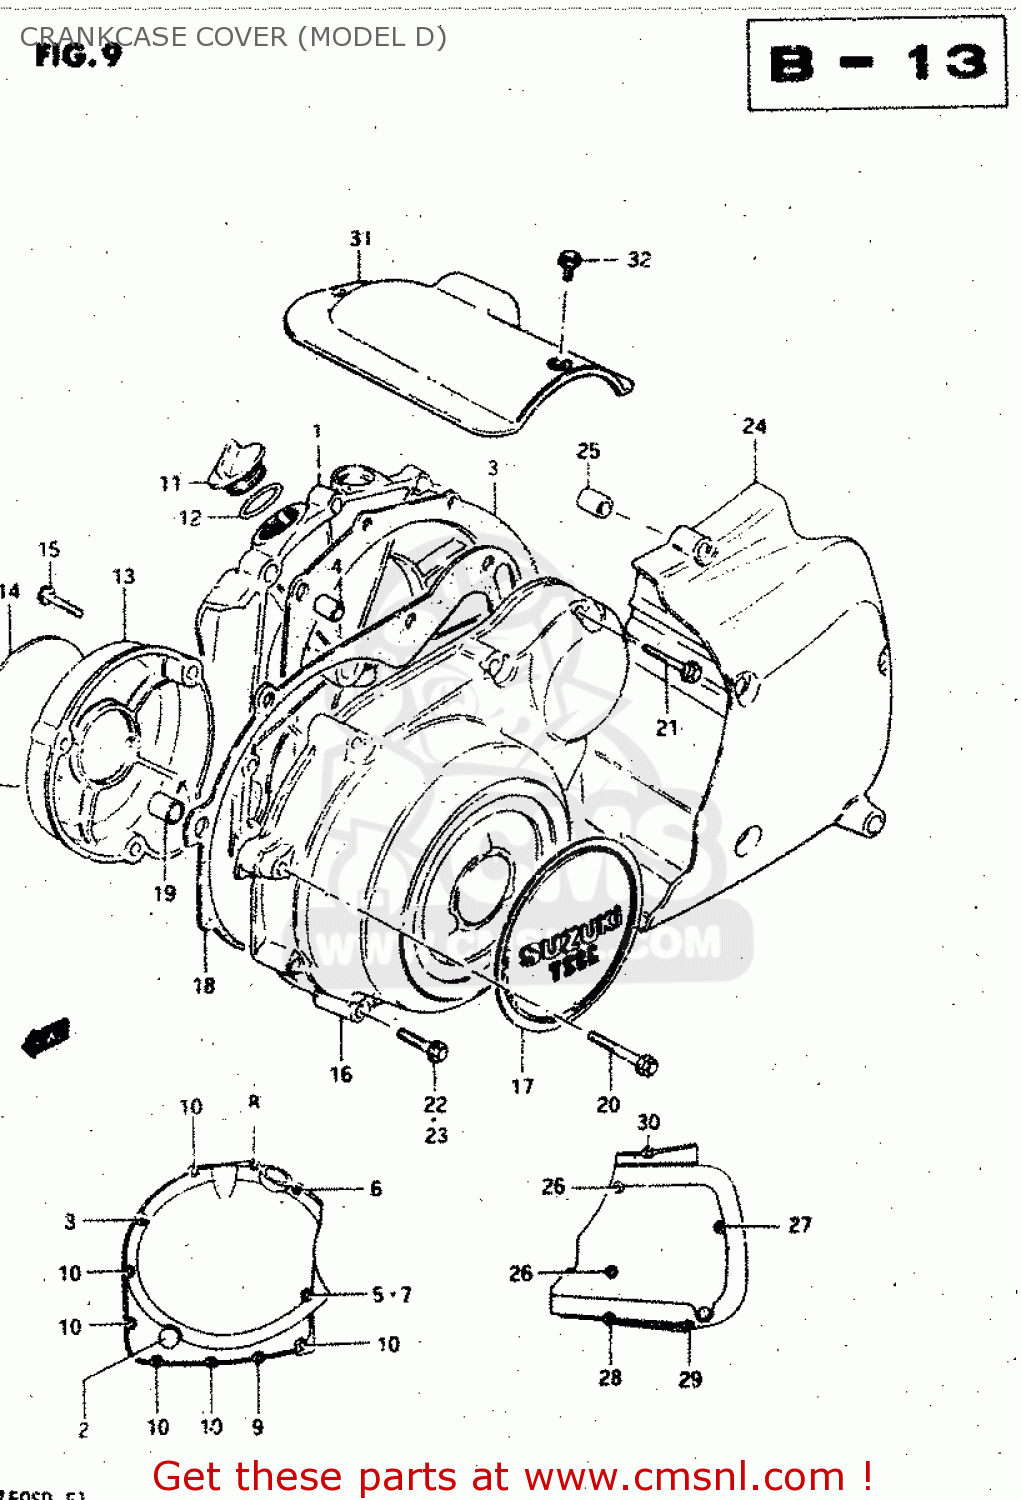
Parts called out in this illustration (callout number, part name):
1	COVER,CLUTCH
2	LENS,OIL LEVEL CHECK
3	GASKET,CLUTCH COVER (MCA)
4	PIN
5	WASHER
6	BOLT 6X40
7	BOLT 6X35
8	BOLT 6X30
9	BOLT 6X25
10	BOLT 6X20
11	CAP
12	O RING(D:2.2,ID:32)
13	COVER,CONTACT BREAKER
14	EMBLEM
15	BOLT 5X30
16	COVER
17	EMBLEM,MAGNETO COVER
18	GASKET,MAGNETO COVER (MCA)
19	PIN
20	BOLT
21	BOLT 6X40
22	BOLT 6X35
23	BOLT 6X30
24	COVER,ENGINE SPROCKET
25	PIN
26	BOLT (6X95)
27	BOLT (6X85)
28	BOLT (6X70)
29	BOLT (6X55)
30	BOLT 6X30
31	COVER,STARTER MOTOR
32	BOLT
